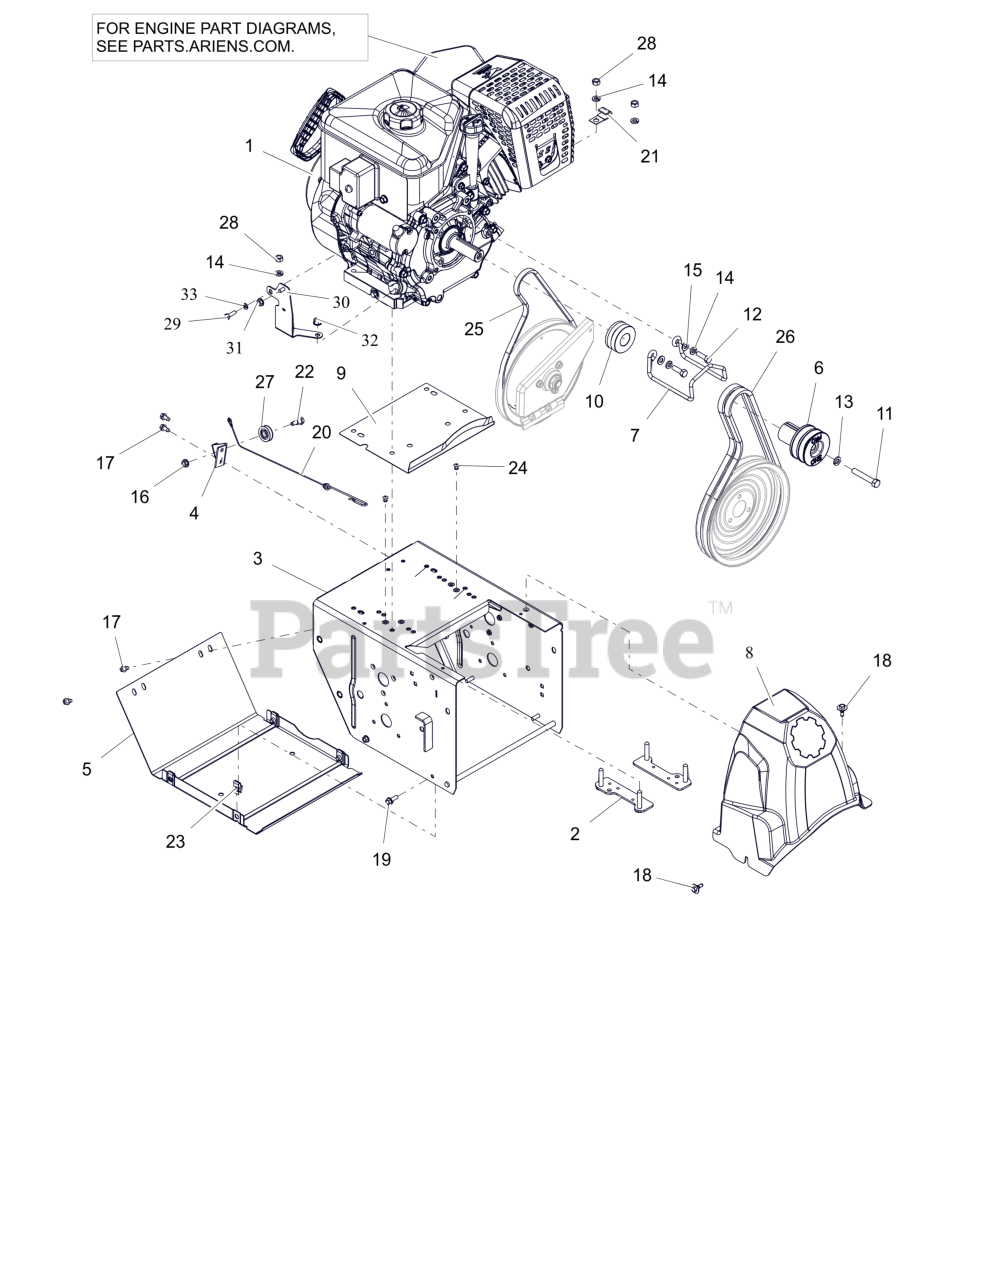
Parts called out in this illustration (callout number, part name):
1	ENGINE,EFI369 GEN3 120V/60W
2	STRAP, BOLT-LARGE
3	FRAME, MAIN - 14GA DELUXE (ORANGE)
4	BRACKET, CABLE PULLEY
5	COVER, BOTTOM
6	SHEAVE,ATTACHMENT-SHO 2 GRV
7	FINGER, BELT
8	COVER, BELT
9	BAFFLE, WATER - LARGE BLOCK
10	SHEAVE, TRACTION (KEYLESS)
11	BLT, HEX .38-24X2.25 G5 ZCC
12	BLT, HEX 0.3125-24X1 G5 ZCC
13	WSHR,LK-REG .375X.094 ZCC
14	WSHR, LK-HVY .312X.097 ZCC
15	WSHR,FLT .344X.688X.065 ZCC
16	NUT-LK-TOP-FLG .250-20 GF ZCC
17	SCR-TAP .25-20X.50 HWH ZCC
18	SCR-TAP .25-20X.5 CAPTIVE
19	BLT, HWH .25-20X.75 G5 ZCC
20	CABLE, LOWER TRACTION,SS & PRO
21	J-CLAMP
22	BOLT, SHLDR -.375 X .375 X .25-20
23	NUT-RTNR .25-20X.56
24	RVT, POP .1875 ZCC
25	V-BELT, 3L-WRAPPED
26	V-BELT, HA-RAW EDGE (SET)
27	PULLEY, CABLE
28	NUT, HEX .312-18 ZCC
29	BLT,HEX M6-1X20 G8.8 ZC120
30	WLDMT- LG BLOCK FUSE MOUNT
31	NUT-LK-CTR-FLG .25-20 ZC120
32	NUT,LK-CTR-FLG .31-18 GF ZCC
33	WSHR,LK-REG .250X.062 ZCC
